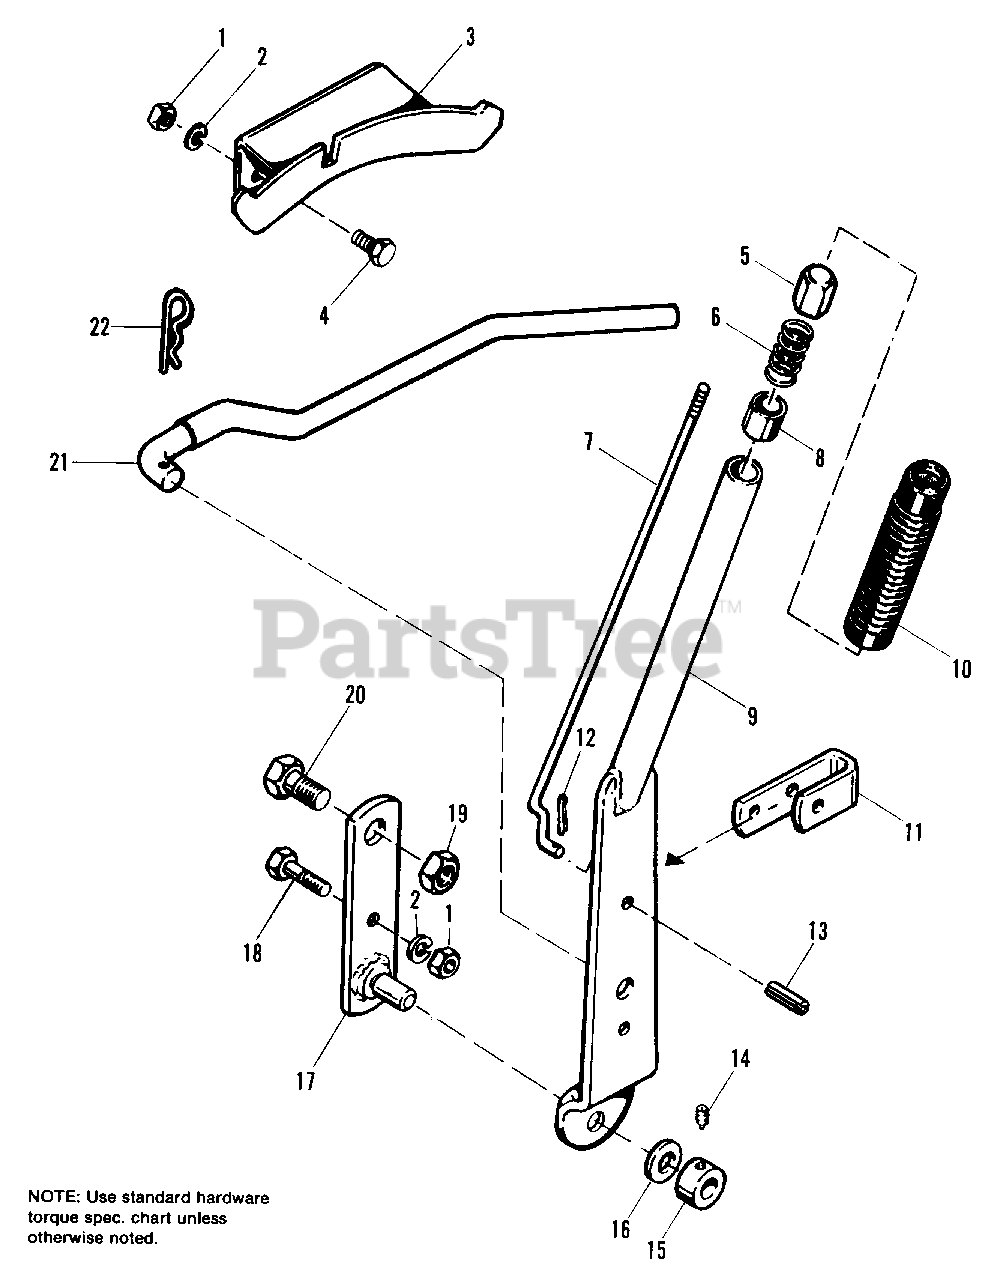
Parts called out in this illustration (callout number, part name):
1	NUT, Hex, Full, 3/8-16
2	LOCKWASHER, 3/8
3	QUADRANT ASSY. (Late model tractor)
4	CAPSCREW, Hex Hd., 3/8-18 x 3/4
5	BUTTON, Thumb
7	ROD, Latch, R.H.
9	LEVER ASSY., Lift, R.H.
10	GRIP, Handle
11	LATCH, Lift Lever
12	COTTER PIN, 3/32 x 3/4
13	PIN, Spring, 3/8 x 1
14	SETSCREW, Sq. Hd., 5/16-18 x 1/2
15	COLLAR, Set
16	WASHER, Plain, 1/2
17	LEVER ASSY.
18	CAPSCREW, Hex Hd., 3/8-16 x 1-1/4
19	LOCKNUT, Hex, Jam, 1/2-13
20	CAPSCREW, Hex Hd., 1/2-13 x 1
21	ROD, Lift
22	PIN, Ouick
22	ROD, Lift
22	SPACER
22	WASHER, Plain
22	LEVER, Lift
22	CAPSCREW, Hex Hd., 7/16-14 x 1/2
22	LOCKWASHER, 5/16
22	WASHER, Plain, 4/16
22	CAPSCREW, Hex Hd., 5/16-18 x 5/8
22	CAPSCREW, Hex Hd., 3/8-16 x 7/8
22	CAPSCREW, Hex Hd., 5/16-18 x 3/4
22	NUT, Retainer, 5/16-18
22	LOCKWASHER, 7/16
22	QUADRANT ASSY., Early Model Tractors
